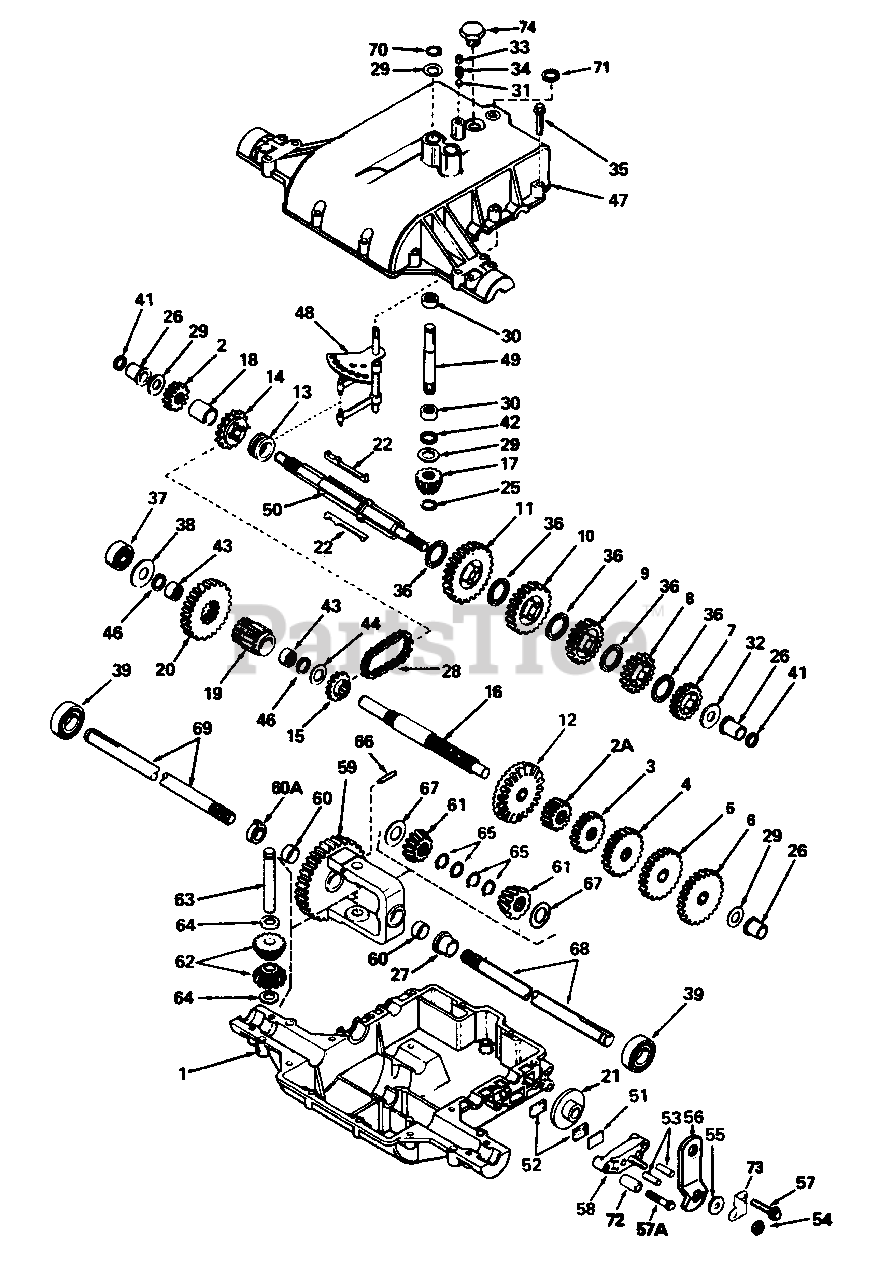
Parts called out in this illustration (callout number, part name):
1	CASE, Transaxle
2	GEAR, Spur (15 Teeth)
2A	GEAR, Spur (12 Teeth)
3	GEAR, Spur (20 Teeth)
4	GEAR, Spur (25 Teeth)
5	GEAR, Spur (28 Teeth)
6	GEAR, Spur (30 Teeth)
7	GEAR, Spur (20 Teeth)
8	GEAR, Spur (22 Teeth)
9	GEAR, Spur (25 Teeth)
10	GEAR, Spur (30 Teeth)
11	GEAR, Spur (37 Teeth)
12	GEAR, Bevel (42 Teeth)
13	COLLAR, Shift
14	SPROCKET (14 Teeth)
15	SPROCKET (10 Teeth)
16	SHAFT, Counter
17	BEVEL PINION, Input
19	PINION, Output
20	GEAR, Output
21	DISK, Brake
25	RING, Retaining
26	BUSHING, Flanged
27	BUSHING, Flanged
28	CHAIN, Roller (No. 41 Chain, 22 Links)
29	WASHER, Thrust
30	BEARING, Needle
31	BALL, Steel
32	WASHER, Thrust
33	SCREW, Set, 3/8-16 x 3/8
35	SCREW, Hex Hd., Thread Forming, 1/4-20 x 1-1/4
36	WASHER, Thrust
37	BEARING, Ball
38	WASHER, Flat
39	BEARING, Ball
41	SEAL, Square Cut
42	SEAL, Square Cut
43	BEARING, Needle
44	WASHER, Flat
46	SEAL, Square Cut
47	COVER, Transaxle
48	ROD & FORK ASSY., Shift
49	SHAFT, Input
50	SHAFT, Brake
51	PLATE, Brake Pad
52	PAD, Brake
53	PIN, Dowel
54	LOCKNUT, 5/16-24
55	WASHER, Flat
56	LEVER, Brake
57	SCREW, Hex Hd., Thread Forming, 1/4-20 x 1-1/4
57A	SCREW, Hex Hd., Thread Forming, 1/4-20 x 2-1/4
58	HOLDER, Brake Pad
59	GEAR ASSY., Differential (Incl. 2 of Ref. No. 60)
61	GEAR, Bevel
62	PINION, Bevel
63	PIN, Drive
64	WASHER, Thrust
65	RING, Retaining (Pkg. of 2)
66	PIN, Roll
67	WASHER, Thrust
68	AXLE (14-3/8" Long)
69	AXLE (12-1/2" Long)
70	RING, Retaining
71	SEAL, Square Cut
73	BRACKET, Brake Lever
74	PLUG, Threaded
